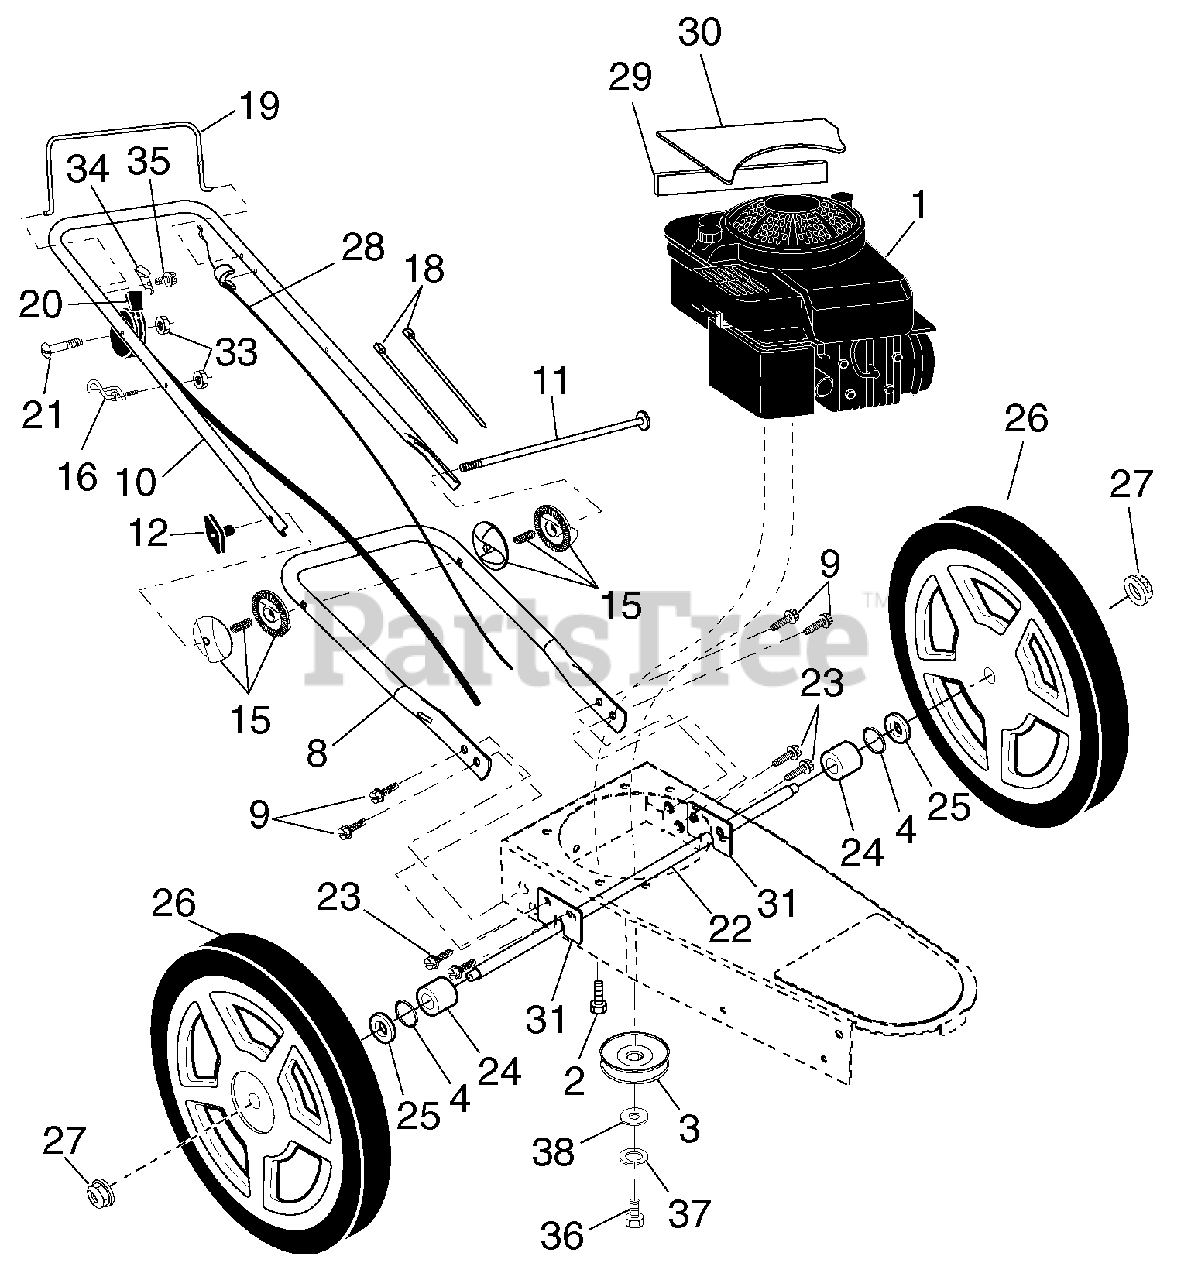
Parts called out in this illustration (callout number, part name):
2	Bolt, Engine Mounting 3/8-16
3	Pulley, Engine
4	Washer, Flat
8	Handle, Lower
9	Screw, Hex Washer Head 5/16-18 x 3/4
10	Handle, Upper
11	Bolt, Handle
12	Knob, Handle
15	Handle Adjuster Assembly
16	Guide, Rope
18	Wire Tire
19	Control Bar
20	Throttle Control
21	Screw, Hex Washer Head
22	Axle Shaft Assembly
23	Screw, Hex Washer Head 5/16-18 x 3/4
24	Washer, Axle
25	O-Ring
26	Wheel, 12 x 1-3/4
27	Locknut, Hex 3/8-16
28	Drive Control Cable
29	Decal, Warning
30	Decal, Warning
31	Bracket, Support, Axle Shaft
34	Bracket, Upstop
35	Screw #10-24 x 5/8
36	Bolt, Hex Head
37	Washer, Lock
38	Washer, Flat, Hardened
38	Manual, Replacement Parts
38	Manual, Operator's, English
38	Manual, Operator's, French
